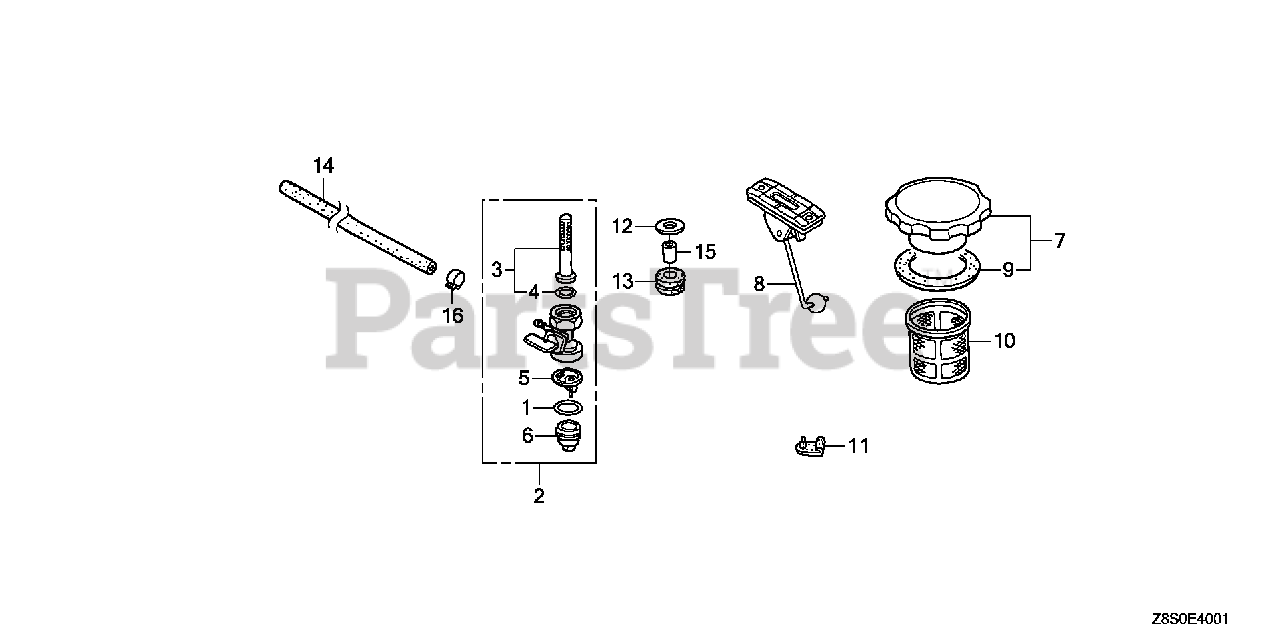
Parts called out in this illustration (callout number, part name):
1	GASKET, FUEL STRAINER CUP
2	PETCOCK ASSY.
3	SCREEN SET, FUEL STRAINER
4	O-RING (9.0X1.3)
5	FILTER, CUP
6	CUP, FUEL STRAINER
7	CAP, FUEL FILLER
8	METER ASSY., FUEL
9	GASKET, FUEL FILLER CAP
10	FILTER, FUEL
12	WASHER, TANK CUSHION
13	RUBBER, TANK CUSHION
15	COLLAR, TANK CUSHION
16	CLAMP, TUBE (D8)
